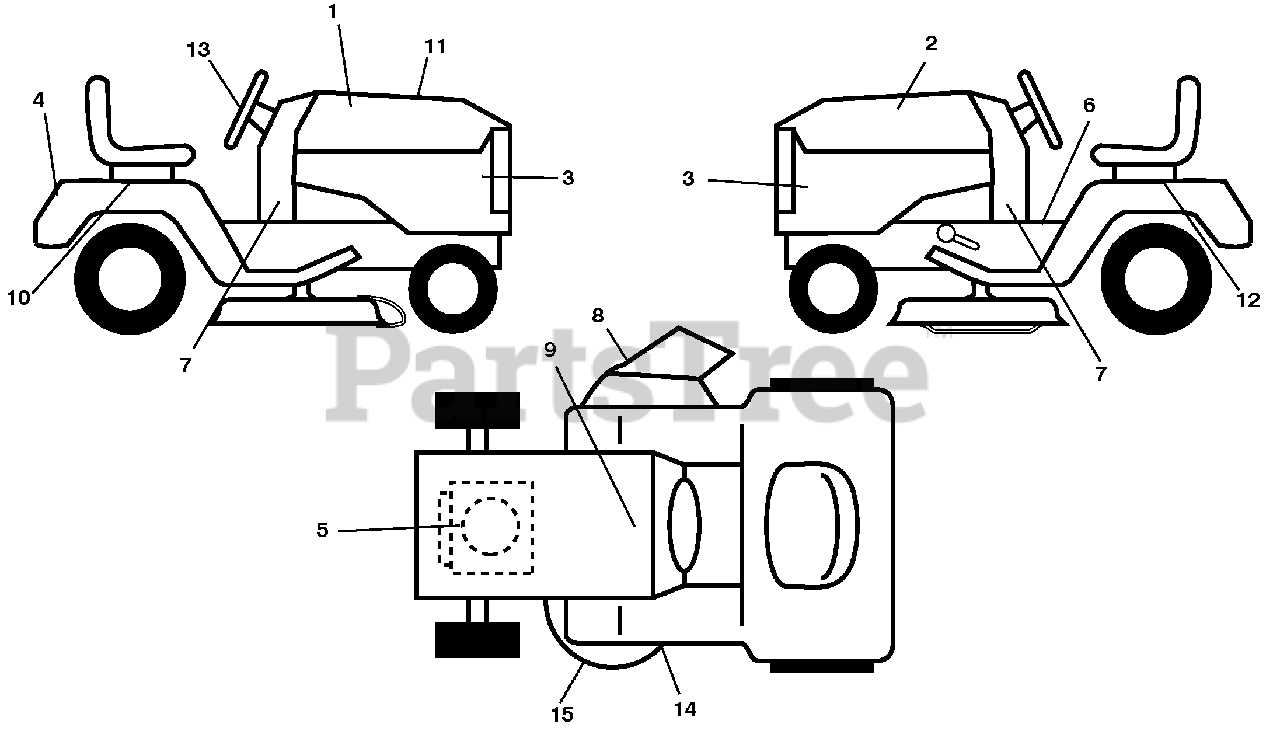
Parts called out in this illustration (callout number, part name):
1	Decal, Hood RH
2	Decal, Hood LH
3	Decal, Side Panel
4	Decal, Fender
5	Decal, Engine
6	Decal, Fender Operator's
7	Decal, Lower Dash
8	Decal, Warning
9	Decal, Battery Dnge/Poi
10	Decal Fender RH
11	Decal, Replacement
12	Decal Fender LH
13	Decal, Steering Wheel
14	Decal, Mower Schematic
15	Decal, Caution
15	Pad Foot Pedal Control
15	Decal, Bypass
15	Pad, Footrest, LH
15	Manual, Operator's (Eng/French)
15	Manual, Parts
